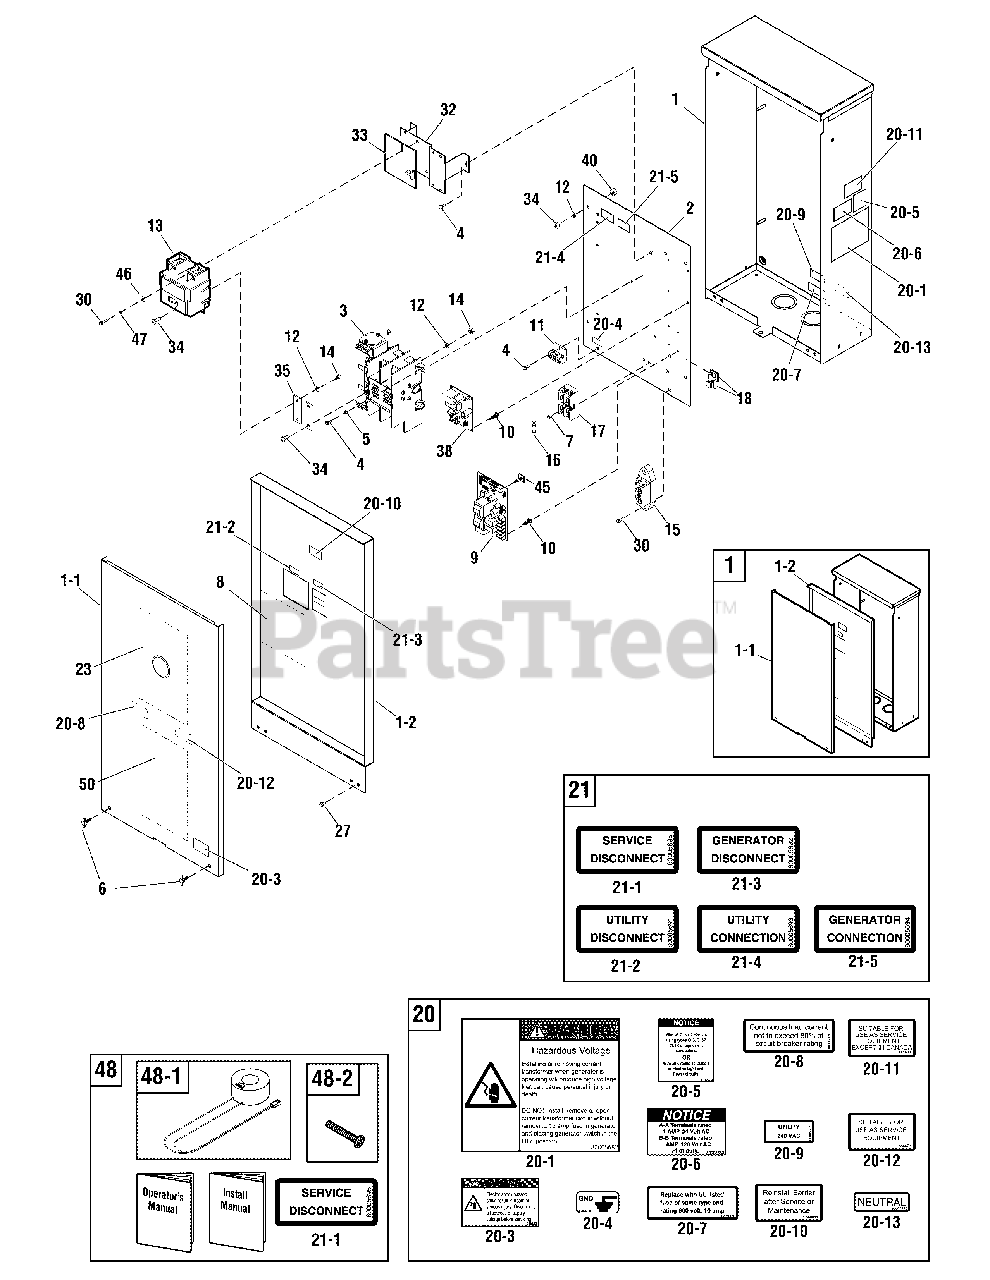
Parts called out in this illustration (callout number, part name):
1	ENCLOSURE
2	BACK PANEL
3	SWITCH, Transfer
4	* TRILOBULAR, #10-32 x 1/2
5	* WASHER, External Tooth, #10
7	* SCREW, Hex Head, Trilobular, #6-32 x 3/8
9	BOARD, Circuit
11	LUG
12	* WASHER, Lock, 1/4
13	BREAKER, Circuit, 200A
14	* NUT, 1/4-20
20	DECAL SHEET - WARNINGS
20-1	DECAL, Warning Voltage
20-3	DECAL, Warning Shock
20-4	DECAL, Ground
20-5	DECAL, Notice
20-6	DECAL, Contacts Rated
20-7	DECAL, Fuse, 10 Amp
20-8	DECAL, Breaker, Circuit
20-9	DECAL, Sensing, Utility
20-10	DECAL, Reinstall After
20-11	DECAL, Not Suitable
20-12	DECAL, Suit. as Service Equip.
20-13	DECAL, Neutral
21	DECAL SHEET-CONNECTIONS
21-1	DECAL, Service Disconnect
21-2	DECAL, Disconnect Utility
21-3	DECAL, Gen Disconnect
21-4	DECAL, Connection, Utility
21-5	DECAL, Connect Gen
27	TRILOBULAR, #10-32 x 3/8"
30	* SCREW, Hex Head, Trilobular, #10-32 x 3/4
34	* SCREW, Phillips Head, 1/4-20 x 3/4
35	BAR, Bus
40	SPACER
46	* WASHER, Flat, #10
47	* WASHER, Lock, #10
48	KIT, Manual
48-1	CURRENT TRANSFORMER
